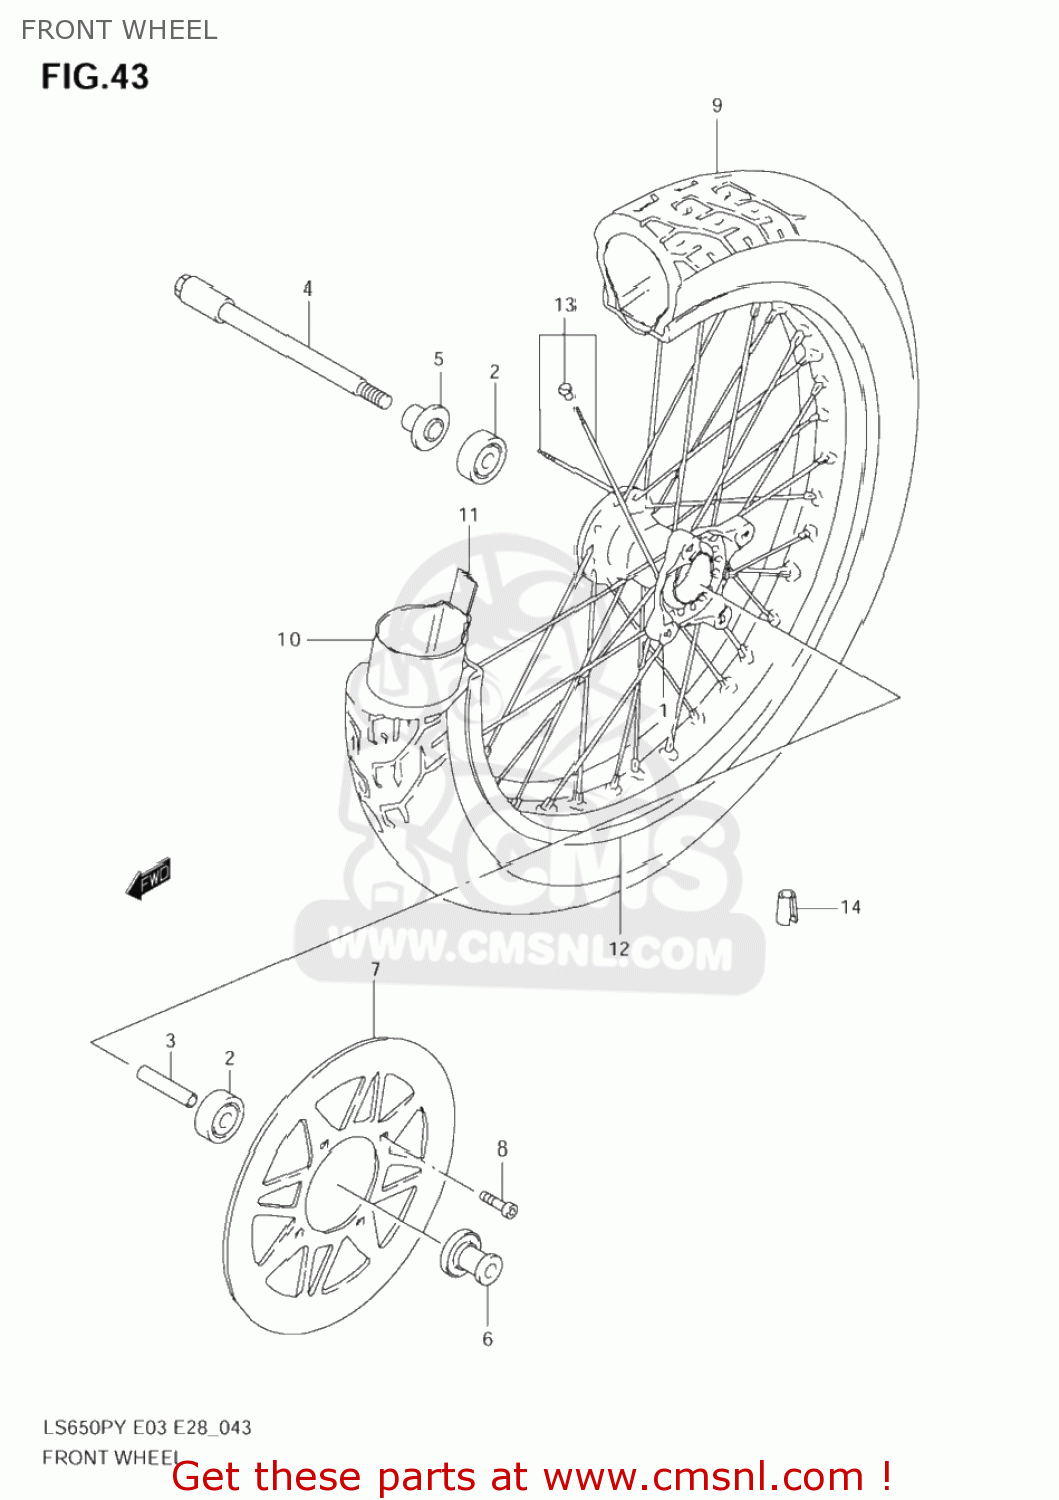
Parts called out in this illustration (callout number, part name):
1	HUB,FR WHEEL
2	BEARING
3	SPACER(15.3X21.7X56)
4	AXLE,FR
5	SPACER,FR AXLE,R
6	SPACER,FR AXLE,L
7	DISC,FR BRAKE
8	BOLT(8X25.5)
9	TIRE,FR(100/90-19 57H)
10	TUBE
11	PROTECTOR,WHL INR TUBE
12	RIM,FR WHEEL WM(2.15X19)
13	SPOKE SET,FRONT
14	BALANCER,WHEEL
